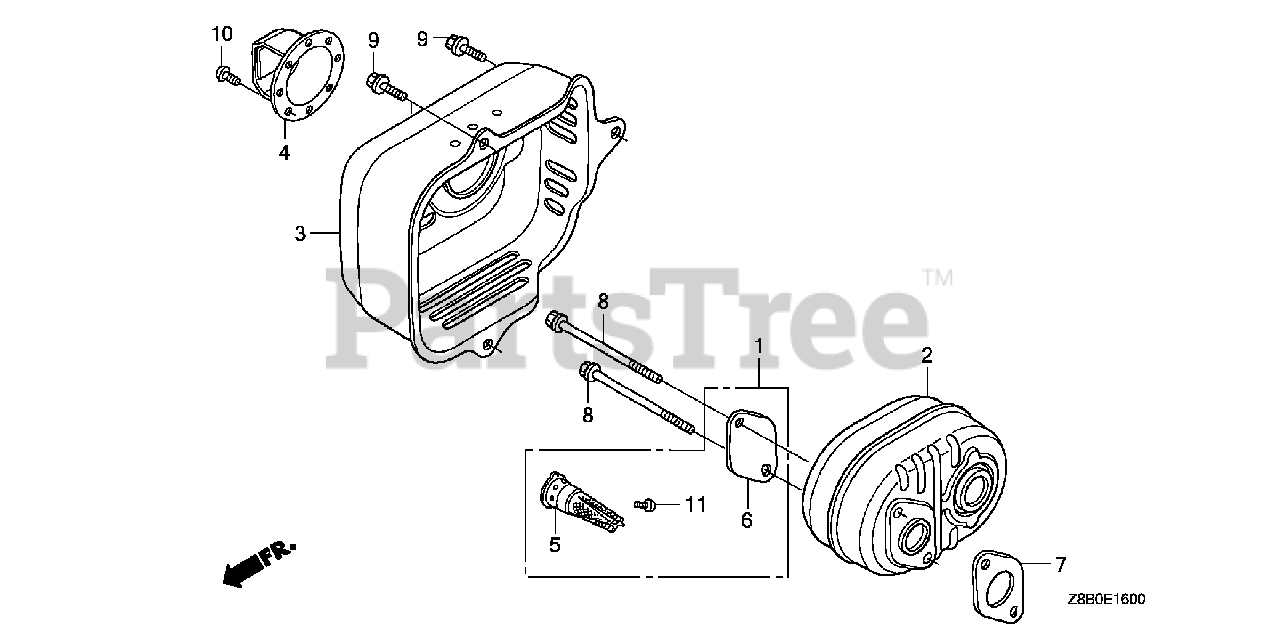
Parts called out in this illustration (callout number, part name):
1	ARRESTER KIT, SPARK
2	MUFFLER
3	PROTECTOR, MUFFLER
5	ARRESTER, SPARK
6	PLATE, ARRESTER NUMBER
7	GASKET, MUFFLER
8	BOLT, FLANGE (6X79) (CT200)
9	BOLT, FLANGE (6X12) (CT200)
11	SCREW, TAPPING (4X6)
